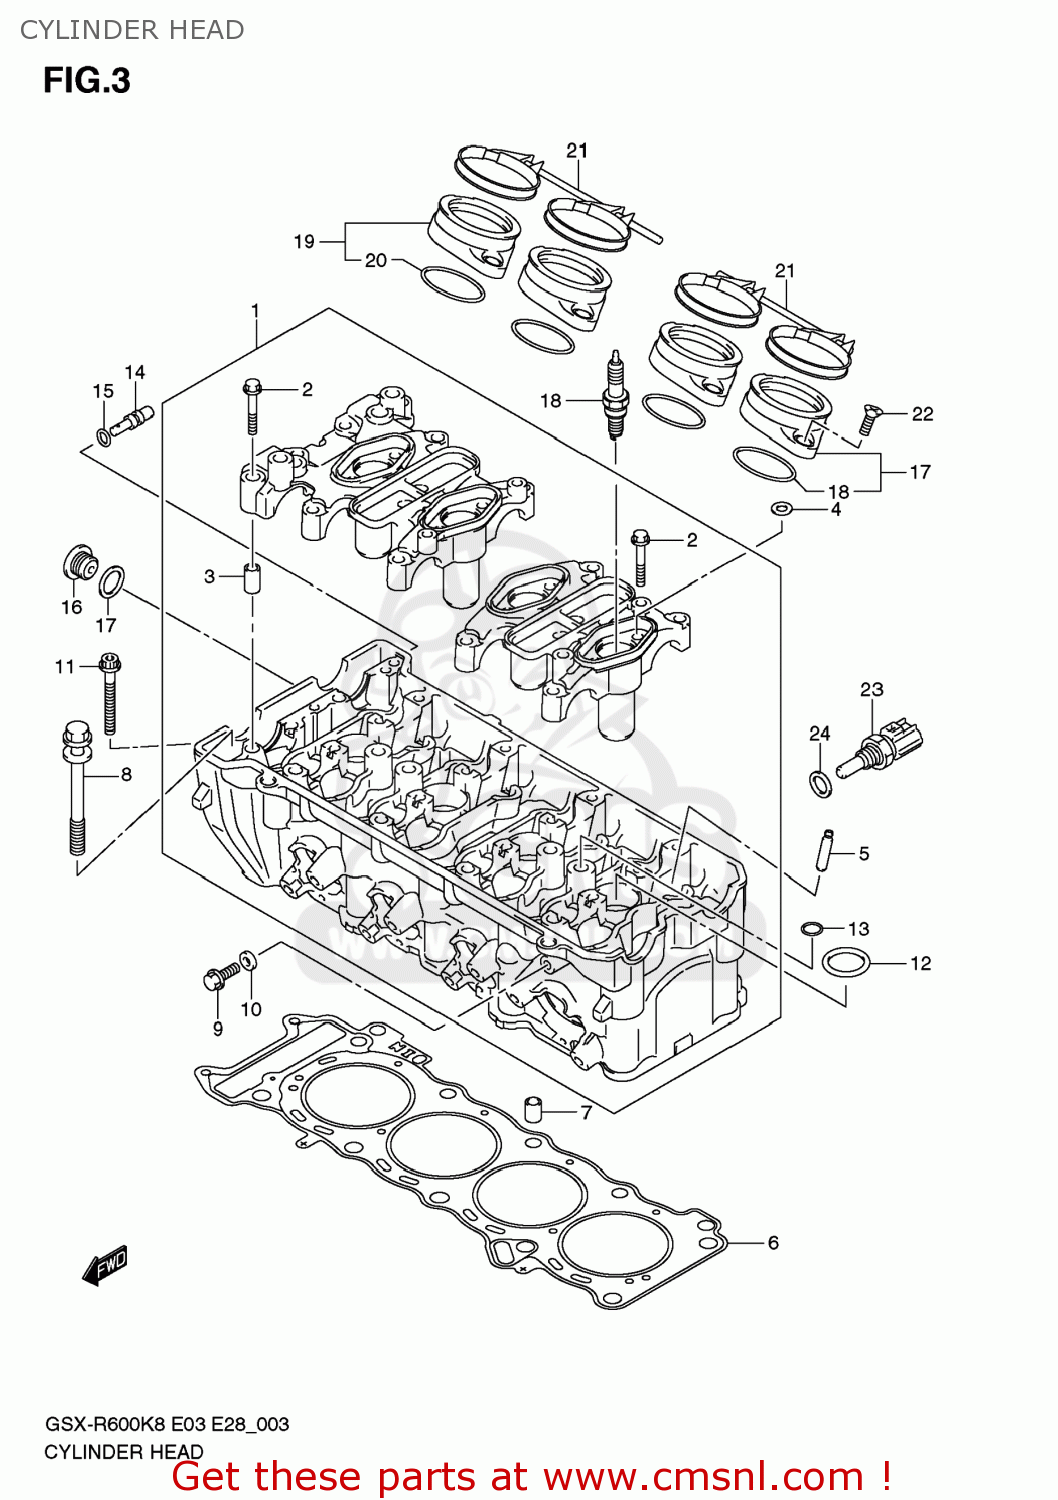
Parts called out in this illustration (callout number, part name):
1	HEAD ASSY,CYLINDER
2	BOLT(6X40)
3	PIN(6.2X8X16)
4	GASKET(6.2X13X1.2) (NAS)
5	GUIDE,VALVE(OS:0.3)
6	GASKET,CYLINDER HEAD (NAS)
7	PIN
8	BOLT,CYLINDER HEAD
9	BOLT(6X12)
10	GASKET(5.8X13X1.2) (NAS)
11	BOLT
12	O-RING
13	O RING(D:2.4,ID:10.8)
14	JET(8)
15	O RING(D:1.2,ID:4)
16	PLUG,16X8
17	GASKET(16X22X0.8) (NAS)
18	PLUG,SPARK(IU27D)
19	PIPE ASSY,INTAKE
20	O RING(D:2.4,ID:41.7)
21	CLAMP,INTAKE PIPE
22	BOLT(6X18.4)
23	SENSOR,TEMP
24	GASKET(12X17X1) (NAS)
